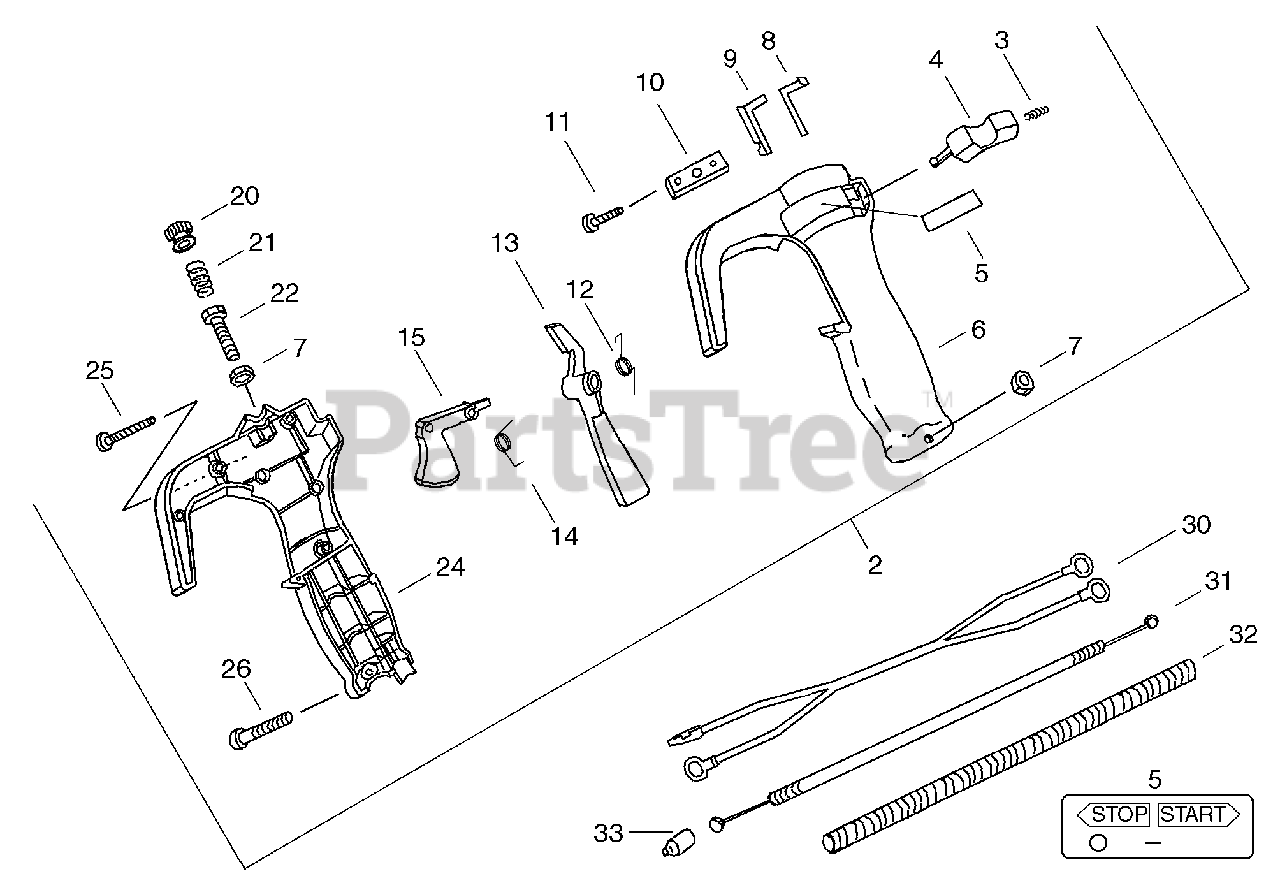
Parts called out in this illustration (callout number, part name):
2	THROTTLE CONTROL ASSY
4	SWITCH, START-STOP
5	LABEL - STOP/START
6	GRIP, HANDLE - LEFT
13	LOCKOUT, THROTTLE
15	TRIGGER, THROTTLE
24	HANDLE, CONTROL - RIGHT
30	WIRE, LEAD
31	CABLE, THROTTLE
32	TUBE, FLEX
33	CAP, DUST
